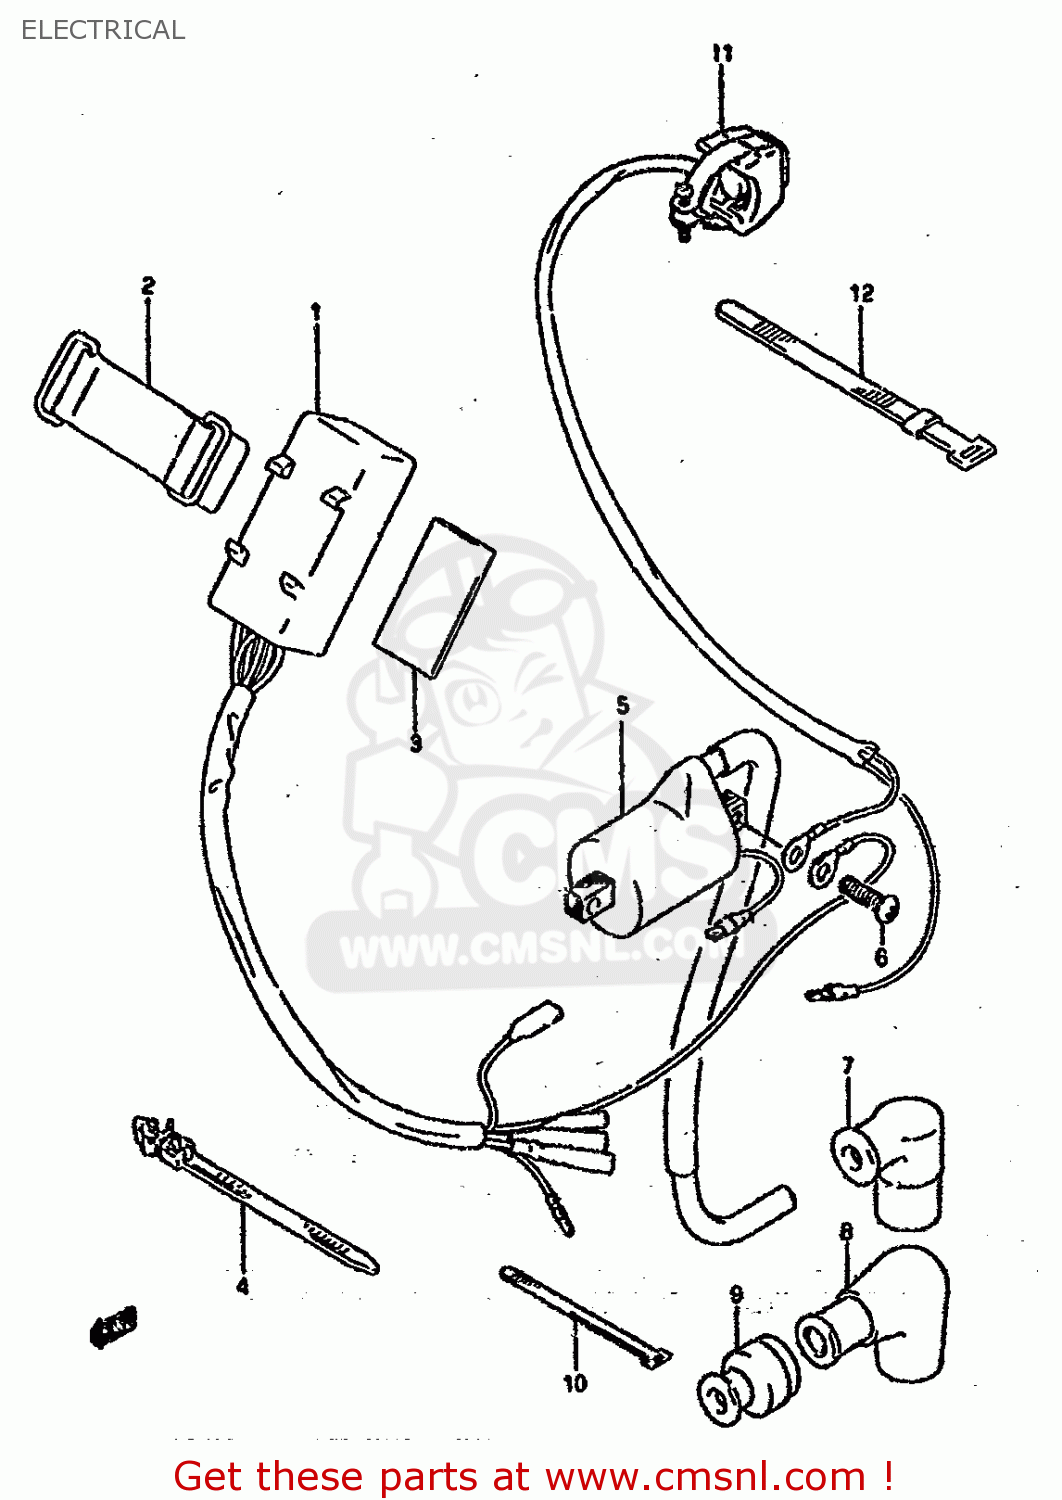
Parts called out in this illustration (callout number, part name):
1	CDI UNIT
2	BAND(L:65)
3	PROTECTOR(170X95X3.0)
4	CLAMP(L:90)
5	COIL ASSY,IGNITION
6	SCREW
7	CAP,SPARK PLUG
8	CAP,SPARK PLUG
9	SEAL,HIGH TENSION CORD
10	CLAMP
11	SWITCH ASSEMBLY
12	CLAMP(L:120)
